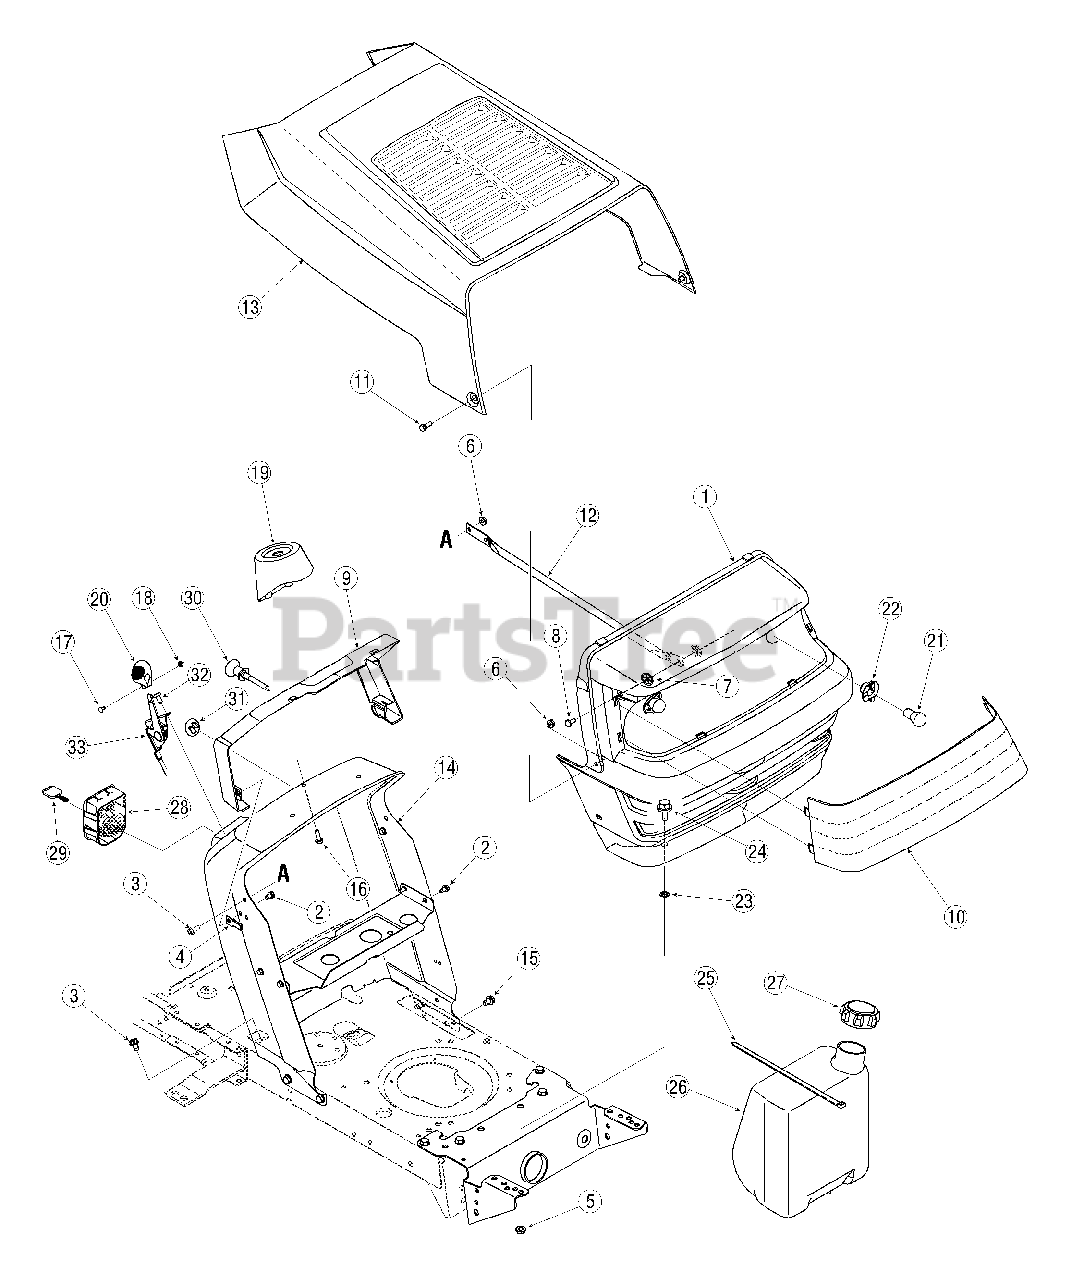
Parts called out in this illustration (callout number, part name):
1	Grille
2	Screw, 1/4-20, 0.500
3	Screw, 1/4-20, 0.750
4	Nut, 1/4-20, Speed U-type
5	Nut, Flange Lock, 5/16-18, Gr F, Nylon
6	Nut, Flange Lock, 1/4-20, Gr F, Nylon
7	Nut, Push-on, .25 Dia
8	Rivet, Flat Head 1/4"
9	Collar, Dash, 0-Style
10	Lens
11	Screw, Shoulder, .375 x .125, 1/4-20
15	Screw, 5/16-18, 0.500
16	Screw, 1/4-15, 0.750
17	Screw, Machine, #8-32, 0.375
18	Nut, Hex, #8-32, Gr A
19	Support, Steering
20	Knob, Control
21	Headlamp, 12V
22	Headlamp Socket
23	Speed Nut, .3125
24	Shoulder Screw, 5/16-18 x .625
25	Cable Tie, 34.75
26	Fuel Tank, 1.5 gal.
27	Fuel Tank Cap
28	Module, Ignition Switch
29	Key
30	Choke Control, 37.5"
32	Screw, 1/4-14, .625
33	Throttle/Choke Control, 25" (Single Cylinder Engine)
